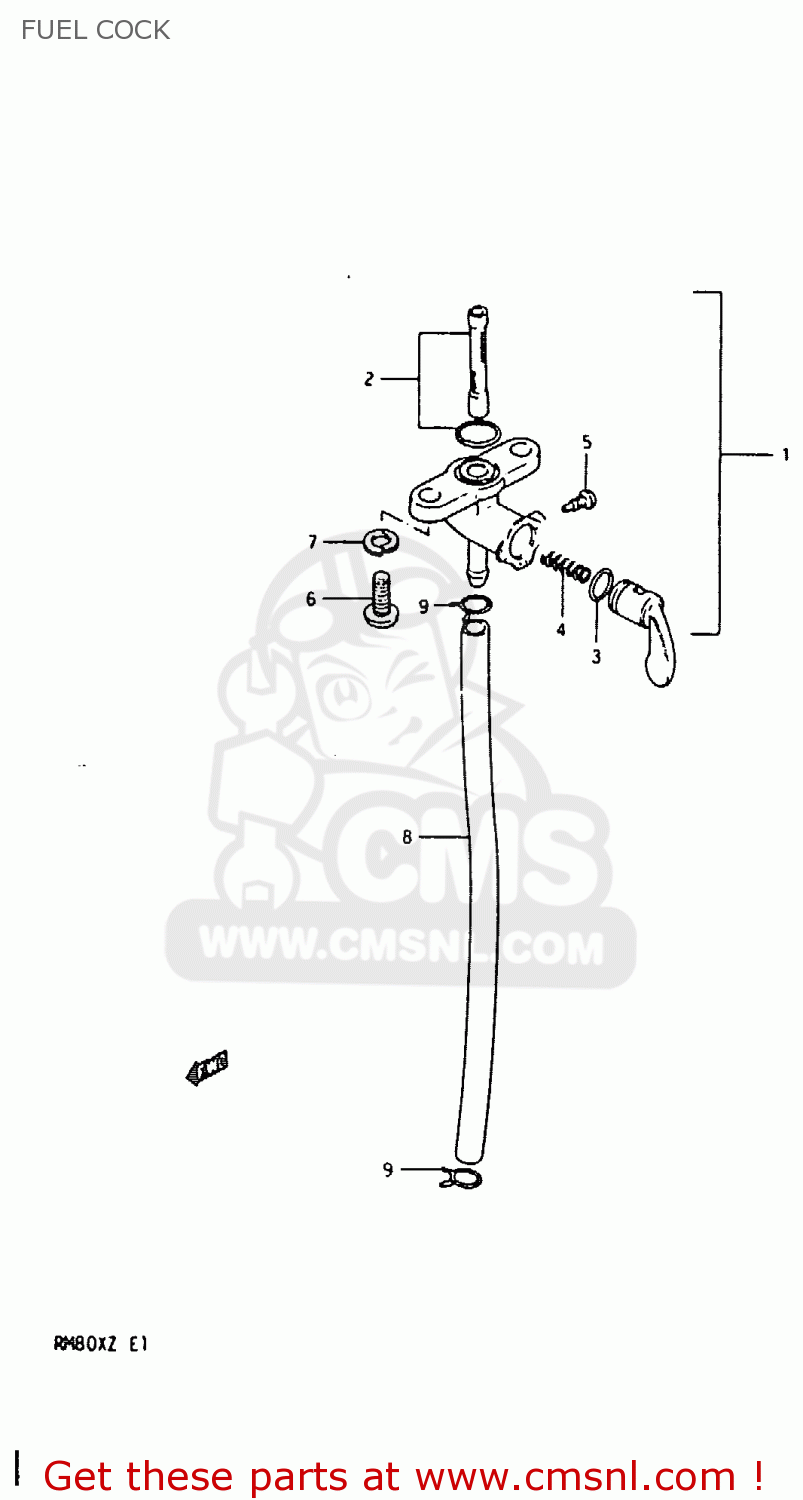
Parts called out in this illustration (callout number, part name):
1	COCK ASSEMBLY,FUEL
2	FILTER SET FUEL
3	O RING,LEVER
4	SPRING,FUEL COCK VALUE
5	SCREW
6	SCREW
7	LOCK WASHER
8	HOSE
9	CLIP
